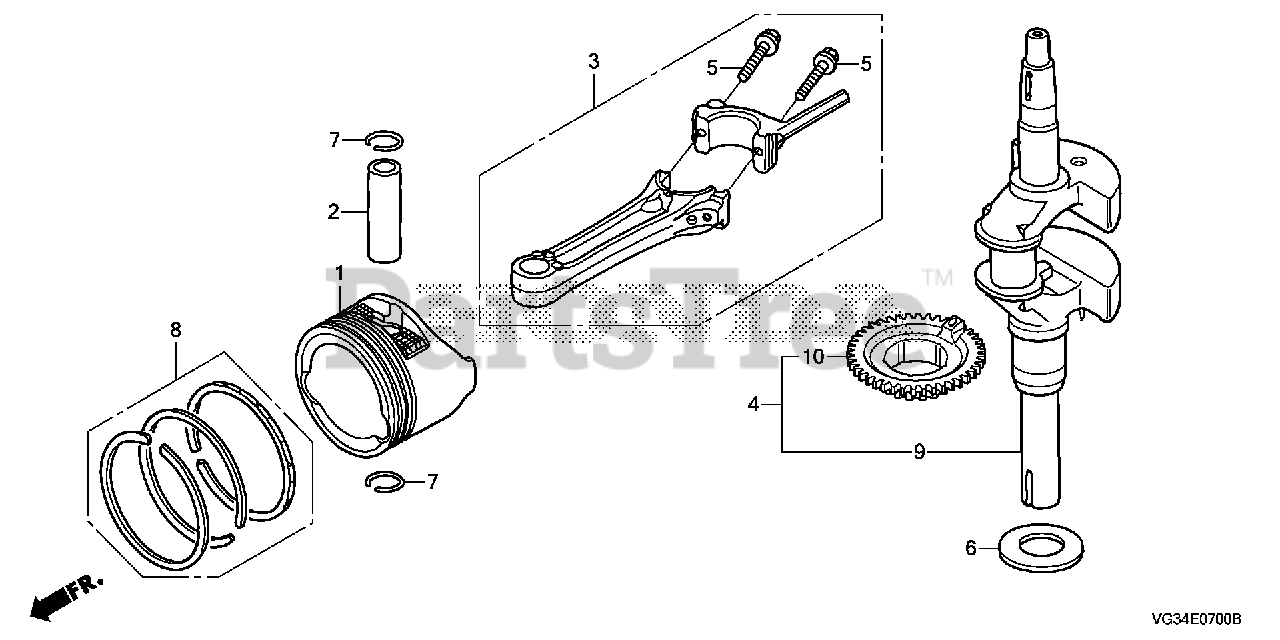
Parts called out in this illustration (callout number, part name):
2	PIN, PISTON
3	ROD ASSY., CONNECTING
4	CRANKSHAFT
5	BOLT, CONNECTING ROD
6	WASHER, THRUST
7	CLIP, PISTON PIN (13MM)
8	RING SET, PISTON (RIKEN)
8	RING SET, PISTON (STD) (TEIKOKU)
